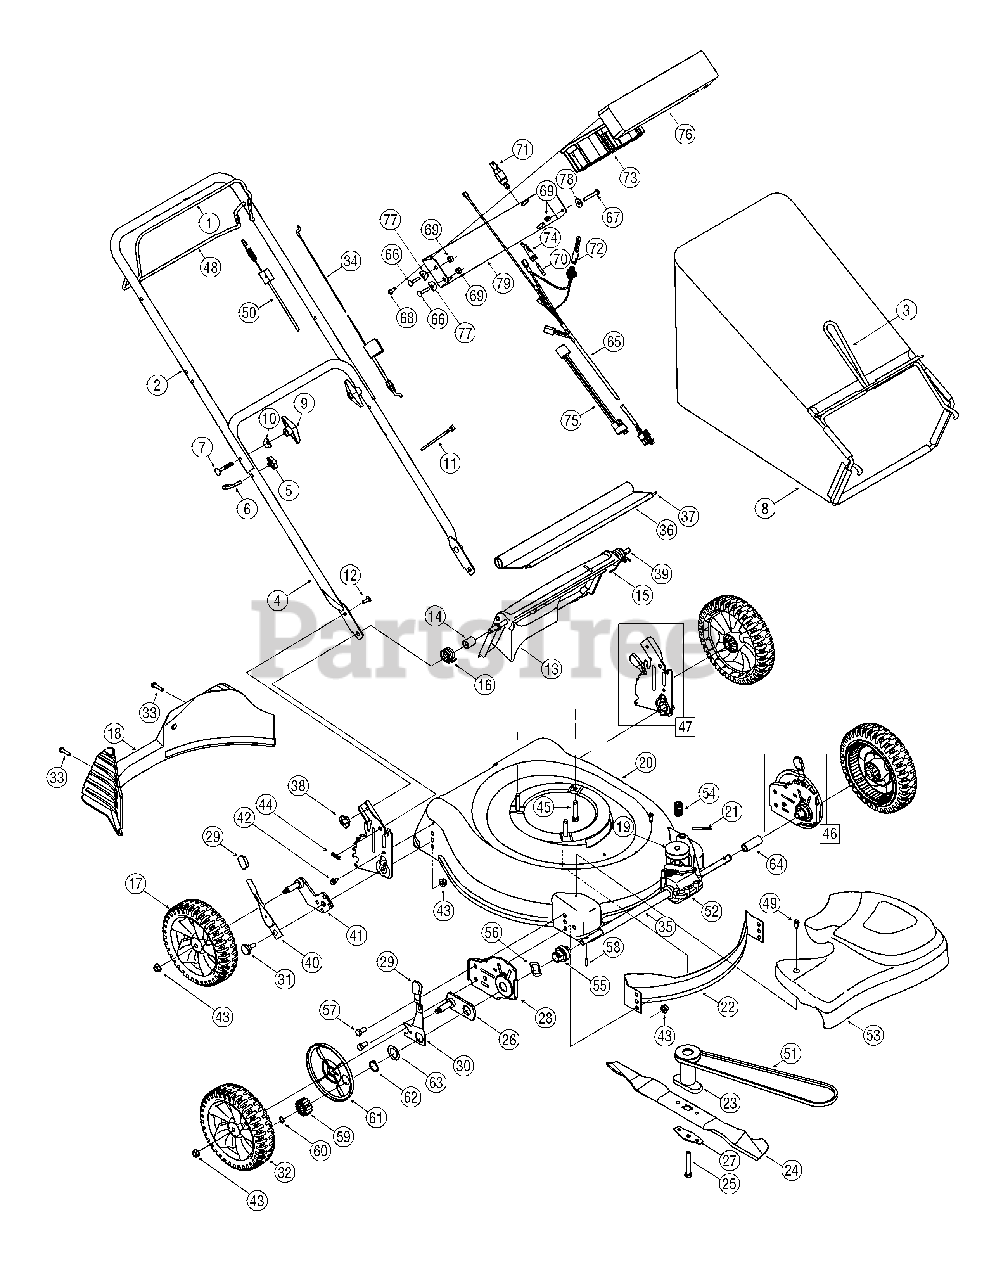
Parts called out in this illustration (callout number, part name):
5	Wing Nut
6	Rope Guide
7	Carriage Bolt ,5/16-18 x 2
8	Grass Bag Assembly
9	Hand Knob
10	Saddle Washer
11	Cable Tie
12	Carriage Bolt ,1/4-20
13	Rear Discharge Door
14	Spacer
15	Torsion Spring - LH
16	Torsion Spring - RH
17	Rear Wheel, 8" x 1.8"
18	Rear Baffle
19	Input Pulley
21	Roll Pin
22	Front Baffle
23	Blade Adapter w/Pulley
24	21" Standard Cut Blade
25	Hex Bolt , 3/8-24 x 2.5
26	Pivot Plate Assembly
27	Blade Bell Support
30	Front Lever - RH
30	Front Lever - LH
31	Shoulder Screw
32	Front Wheel, 8" x 1.8"
33	Screw, 1/4-15 x 1.250
34	Control Cable - 50.56"
35	Sleeve Spacer - RH
36	Trailshield
37	Trailshield Wire
38	Wing Nut, 1/4-20
39	Rear Door Pivot Rod
40	Spring Lever
41	Pivot Arm Assembly - RH
41	Pivot Arm Assembly - LH
42	AB Screw
43	Flange Lock Nut, 3/8-16
44	Hairpin Clip
45	TT Sems Screw, 3/8-16 x 1.00
46	Ht. Adj. Assy. Front - LH
46	Ht. Adj. Assy. Front - RH
47	Rear Handle Bracket Assy. - LH
47	Rear Handle Bracket Assy. - RH
48	Drive Control
49	Shoulder Screw
50	Drive Cable
51	V-Belt
52	Transmission Assembly
53	Front Drive Cover
54	Belt Tension Spring
55	Bearing Assembly
56	Wave Washer
57	Hex Screw
58	Dowel Pin
59	Gear, 14T - RH
59	Gear, 14T - LH
60	Snap Ring
61	Wheel Dust Cap
62	Snap Ring
63	Washer, 1.5" OD
64	Sleeve Spacer - LH
65	Electric Starter Harness Assembly
66	Screw, 1/4-20 x 1.50
67	Screw, 1/4-20 x 1.75
68	Screw, #12-16 x 1.00
69	Hex Lock Nut, 1/4-20
70	7.5 Amp Fuse
71	Key Switch
72	Plug
73	12 Volt Battery
74	Fuse Holder
75	Ext Harness
76	Upper Battery Tray
77	Saddle Washer, .320 x .93 x .060
78	Bell Washer, .265 x .75 x .062
